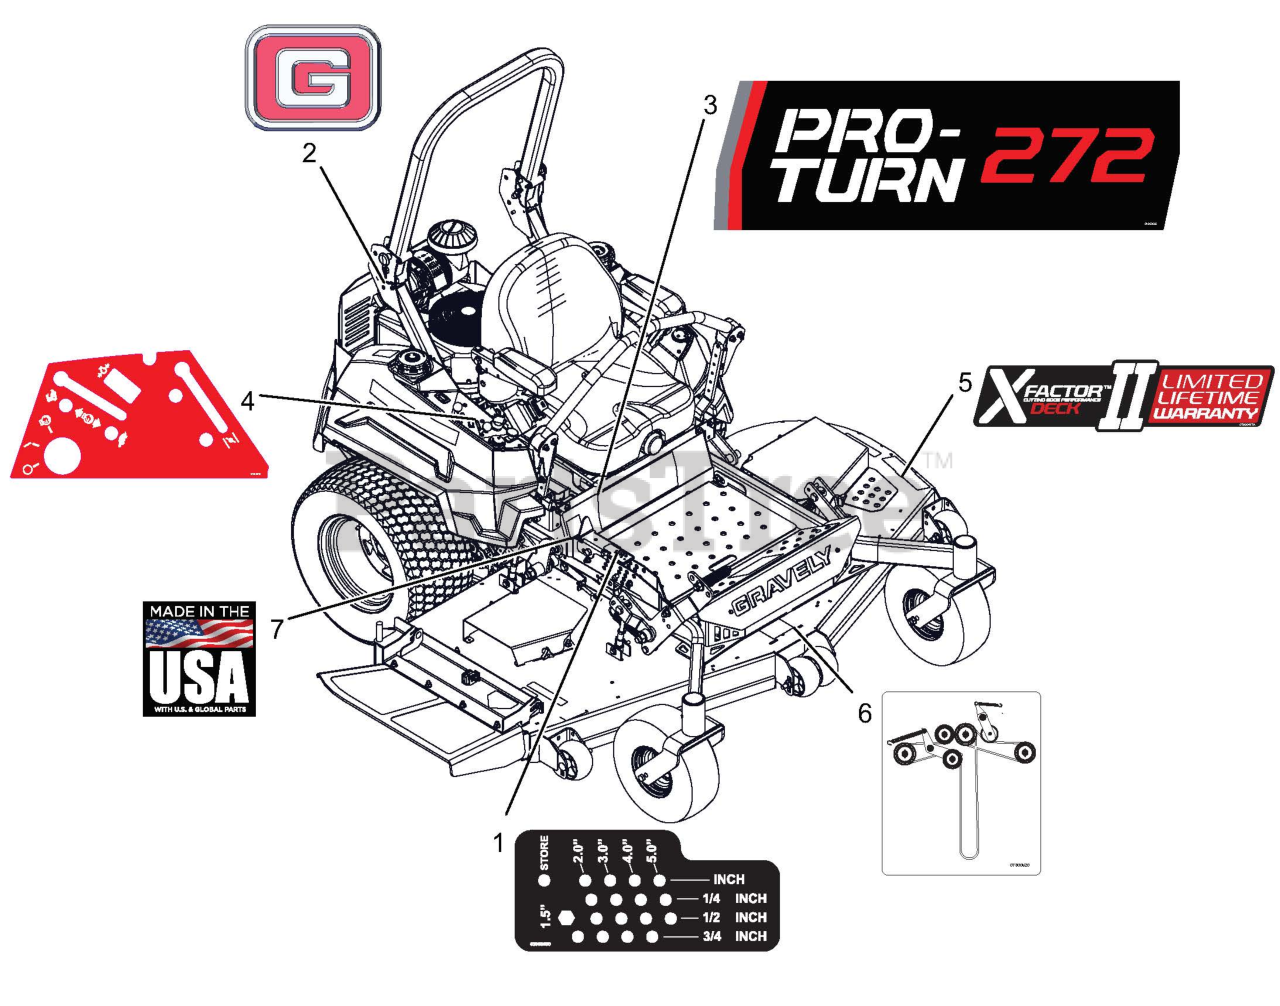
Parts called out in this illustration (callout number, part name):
1	DECAL, HEIGHT OF CUT
2	DECAL, GRAVELY BRAND
3	DECAL, PRO-TURN 272
4	DECAL, NON-EFI CONTROL PANEL
5	DECAL, X-FACTOR DECK
6	DCL,BELT ROUTE-RH BK-SIDE IDLR
7	DECAL, MADE IN USA
